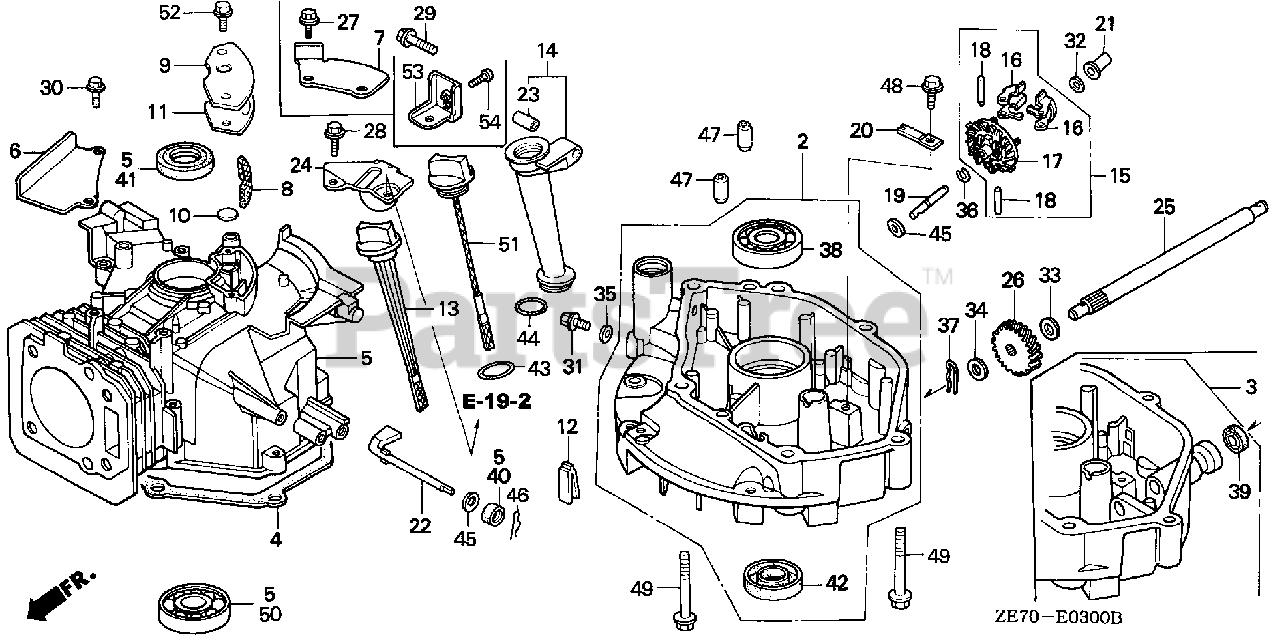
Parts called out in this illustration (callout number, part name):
2	PAN ASSY., OIL (PUSH TYPE)
4	GASKET, OIL PAN
5	CYLINDER ASSY.
6	PLATE, GUIDE
7	PLATE A, GUIDE
8	FILTER, BREATHER
9	COVER, BREATHER
10	VALVE, BREATHER
11	GASKET, BREATHER COVER
12	RUBBER, OIL RETURN
13	DIPSTICK, OIL
14	EXTENSION, OIL FILLER (106MM)
15	GOVERNOR ASSY.
16	WEIGHT, GOVERNOR
17	HOLDER, GOVERNOR WEIGHT
18	PIN, GOVERNOR WEIGHT
19	SHAFT, GOVERNOR HOLDER
20	PLATE, GOVERNOR SHAFT HOLDER
21	SLIDER, GOVERNOR
22	SHAFT, GOVERNOR ARM
23	COLLAR, EXTENSION
27	BOLT, FLANGE (6X12) (CT200)
29	BOLT, FLANGE (6X32)
30	BOLT, FLANGE (6X20) (CT200)
31	BOLT, DRAIN PLUG
32	WASHER, THRUST (6MM)
35	WASHER, DRAIN PLUG (10.2MM)
36	CLIP, GOVERNOR HOLDER
40	OIL SEAL (6X11X4)
41	OIL SEAL (25X38X7)
41	OIL SEAL (25X38X7) (ARAI)
42	OIL SEAL (25.4X40X7)
43	O-RING (22.5X2.2)
44	O-RING (26X2.7)
45	WASHER, PLAIN (6MM)
46	PIN, LOCK (8MM)
47	PIN A, DOWEL (8X14)
48	BOLT, FLANGE (6X12)
49	BOLT, FLANGE (8X50)
50	BEARING, RADIAL BALL (6205)
52	BOLT, FLANGE (6X14)
